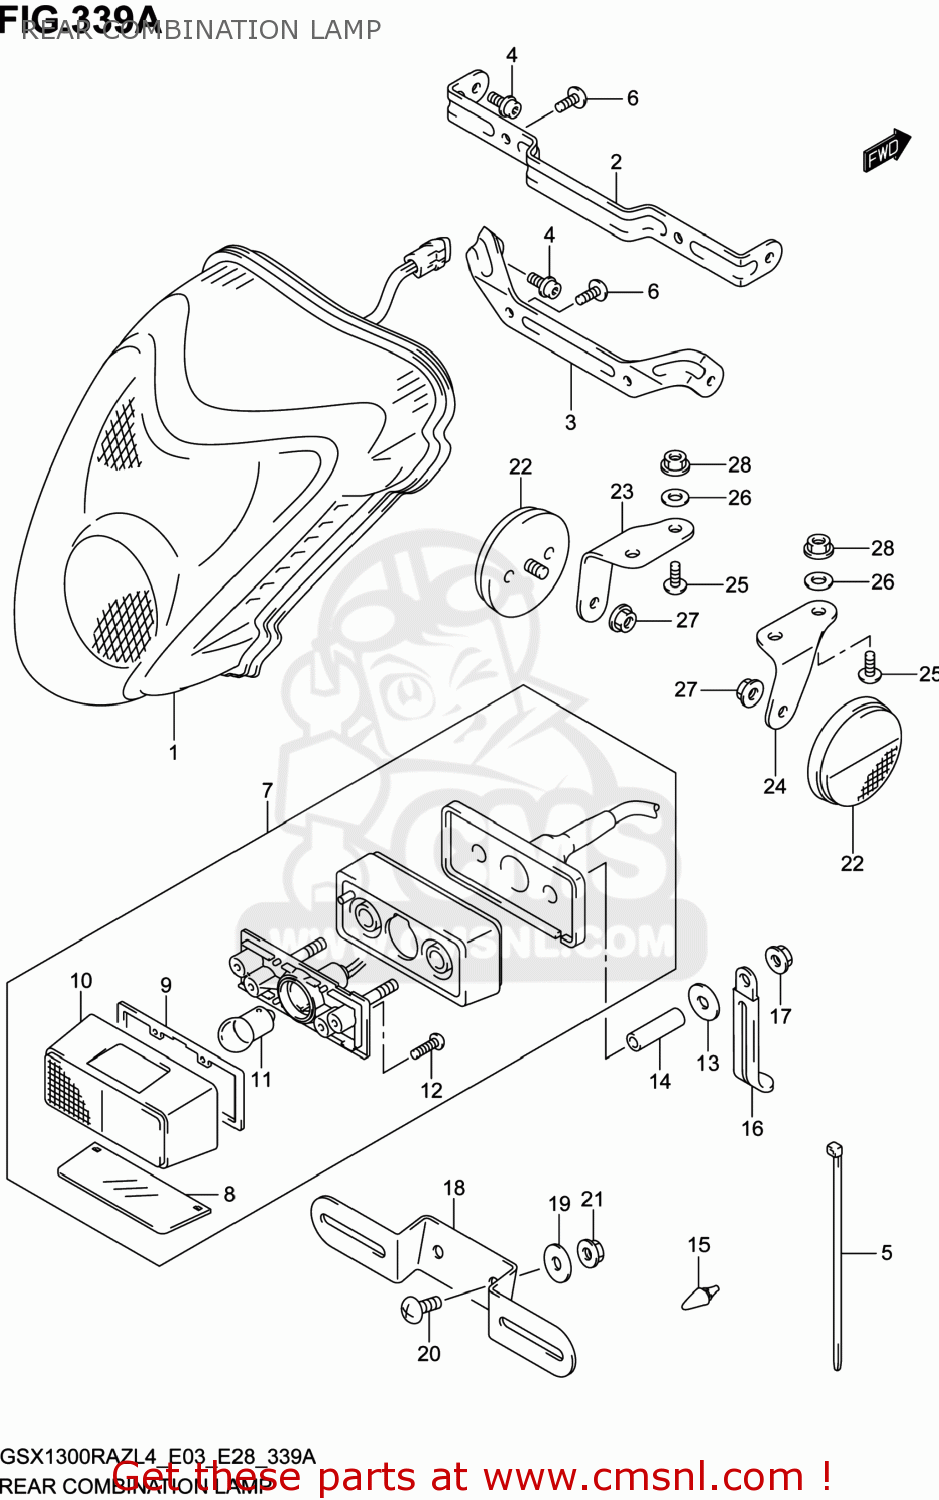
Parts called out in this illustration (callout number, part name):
1	LAMP ASSY,RR COMBINATION
2	BRACKET,RR COMBINATION LAMP
3	BRACKET,RR COMBINATION LAMP
4	BOLT(5X12)
5	CLAMP(L:145)
6	SCREW
7	LAMP ASSY,LICENSE
8	LENS,LICENSE LAMP
9	GASKET (NAS)
10	COVER,LICENSE LAMP
11	BULB(12V5W,BF150-40160A)
12	SCREW
13	WASHER(6.5X20X1.2)
14	SPACER(6.5X9X34)
15	CUSHION
16	CLAMP(L:45)
17	NUT
18	BRACKET,LICENSE PLATE
19	WASHER(6.5X20X1.2)
20	SCREW
21	NUT
22	REFLECTOR ASSY,RR SIDE
23	BRACKET,RR SIDE RR,R
24	BRACKET,RR SIDE RR,L
25	SCREW
26	WASHER(6.5X14X2)
27	NUT
28	NUT
